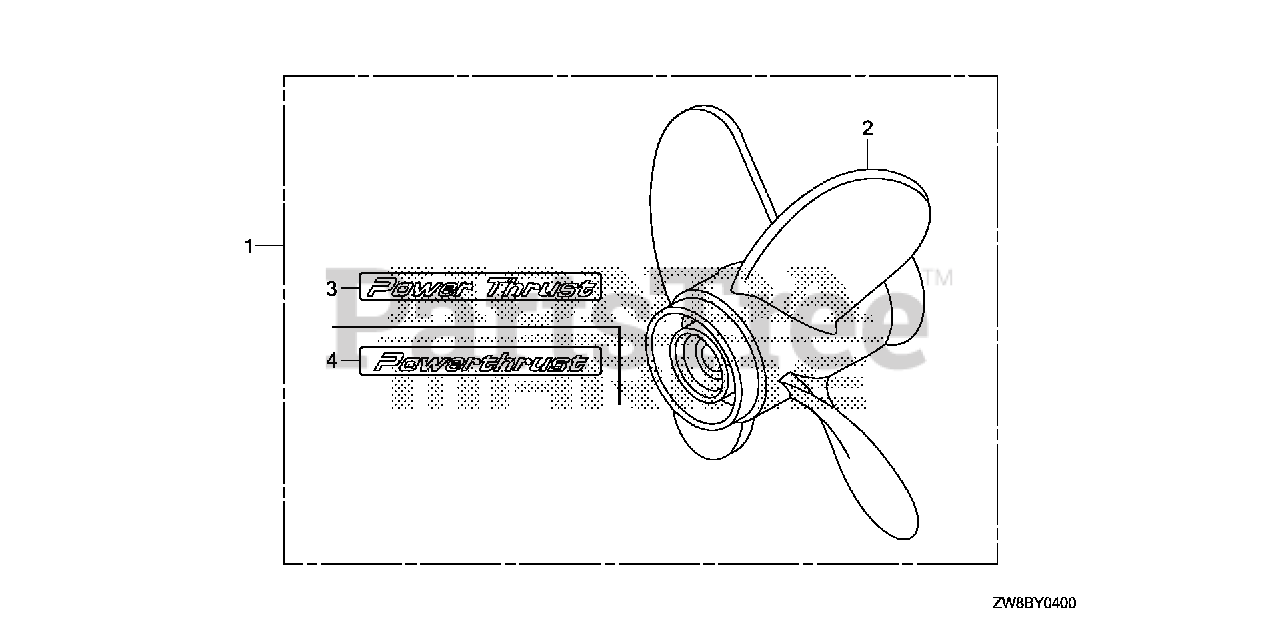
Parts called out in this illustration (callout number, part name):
1	PROPELLER KIT, POWER THRUST
1	PROPELLER KIT, POWER THRUST *NH283* (STIN GRAY)
2	PROPELLER, FOUR BLADES (10X6-1/2 HT) *NH283* (STIN GRAY)
3	MARK, POWER THRUST
